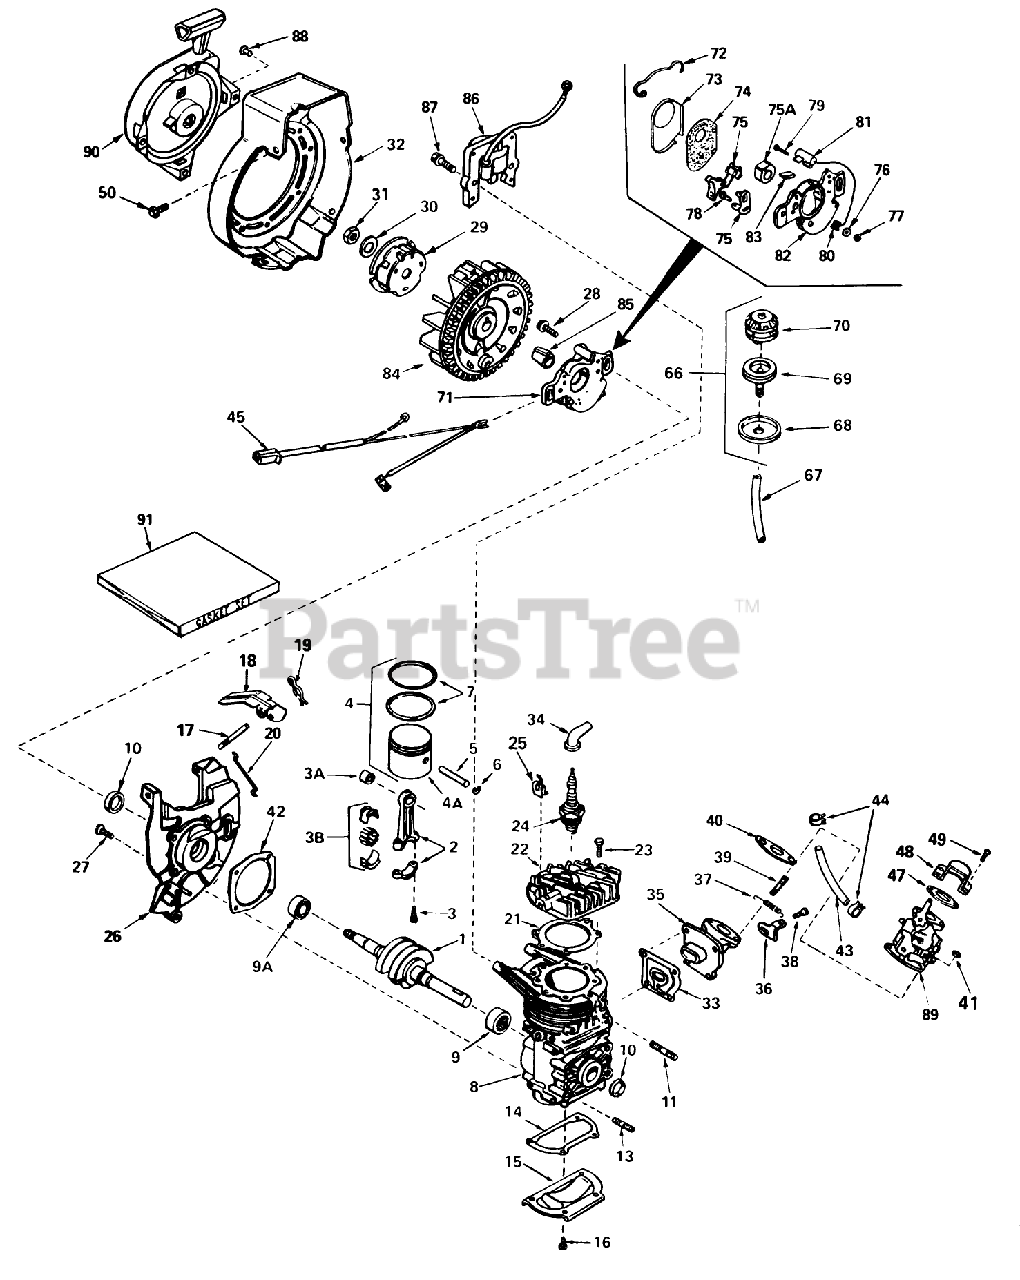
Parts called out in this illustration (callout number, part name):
1	Crankshaft
2	Rod Assembly, Connecting (Incl. #3, 3A 3B)
3	Bolt-Rod, Connecting
3A	Bearing-Cartridge
3B	Bearing Liner Set Needle
4	Piston, Pin Ring Assy. (Incl. Ref. #6 thru 9)
4A	Piston
5	Pin, Piston
6	Ring-Retaning
7	Ring Set
8	Block Assy., Cylinder (Order short block if replacement is required)
9	Bearing-Cartridge
9A	Bearing-Ball
10	Seal-Oil
14	Gasket, Cover
15	Plate, Cover
16	Screw (T-25, 10-24 x 1/2)
17	Shaft, Air Vane
18	Vane Assy., Air
19	Clip,Air Vane
20	Link-Governor
21	Gasket, Head
22	Head-Cylinder
23	Screw (T-30, 1/4-20 x 3/4)
24	Head Adjustment Knob
26	Base Assy., Blowerr Housing (Incl. Ref. #10 17)(used on type 1603, 1603A 1603B)
27	Screw
28	Screw, Hex Washer Hd.
29	Cup-Starter
30	Washer-Spring
31	Nut-Flywheel
32	Housing-Blower
33	Gasket, Port
34	Cover-Spark Plug
35	Elbow Assy., Adapter
36	Lever, Adjusting
37	Spring, Adjusting Lever
38	Screw
39	Stud Carburetor
40	Gasket, Carburetor
41	Locknut
42	Gasket, Shroud Base
43	Line-Fuel
44	Clamp-Line, Fuel
45	Harness, Wire
47	Gasket
48	Baffle-Carburetor
49	Screw
50	Screw-Hex, Hd.
66	Primer Assy.
67	Line, Primer
68	Retainer, Primer Bulb
69	Body, Primer
70	Bulb-Primer
71	Stator Plate Assy. (incl. Nos. 107, 111 thru 118 120)
72	Spring Breaker Box
73	Cover-Dust
74	Gasket Dust
75	Breaker Assy.
75A	Cam, Breaker
76	Washer
77	DECAL
78	Breaker Screw
79	Condenser Screw
80	Terminal, Ground
81	Condenser
82	Stator Plate
83	Felt,Cam Wiper
84	FIywheel
85	SHIELD
86	Lamination Coil Assy. (Incl. No. 42)
87	Screw
88	Rivet, Pop (3/16" dia.) (Can be purchased locally)
89	Carburetor (Incl. Ref. #40)
90	Starter-Rewind
91	Gasket Set (Incl. items marked *)
